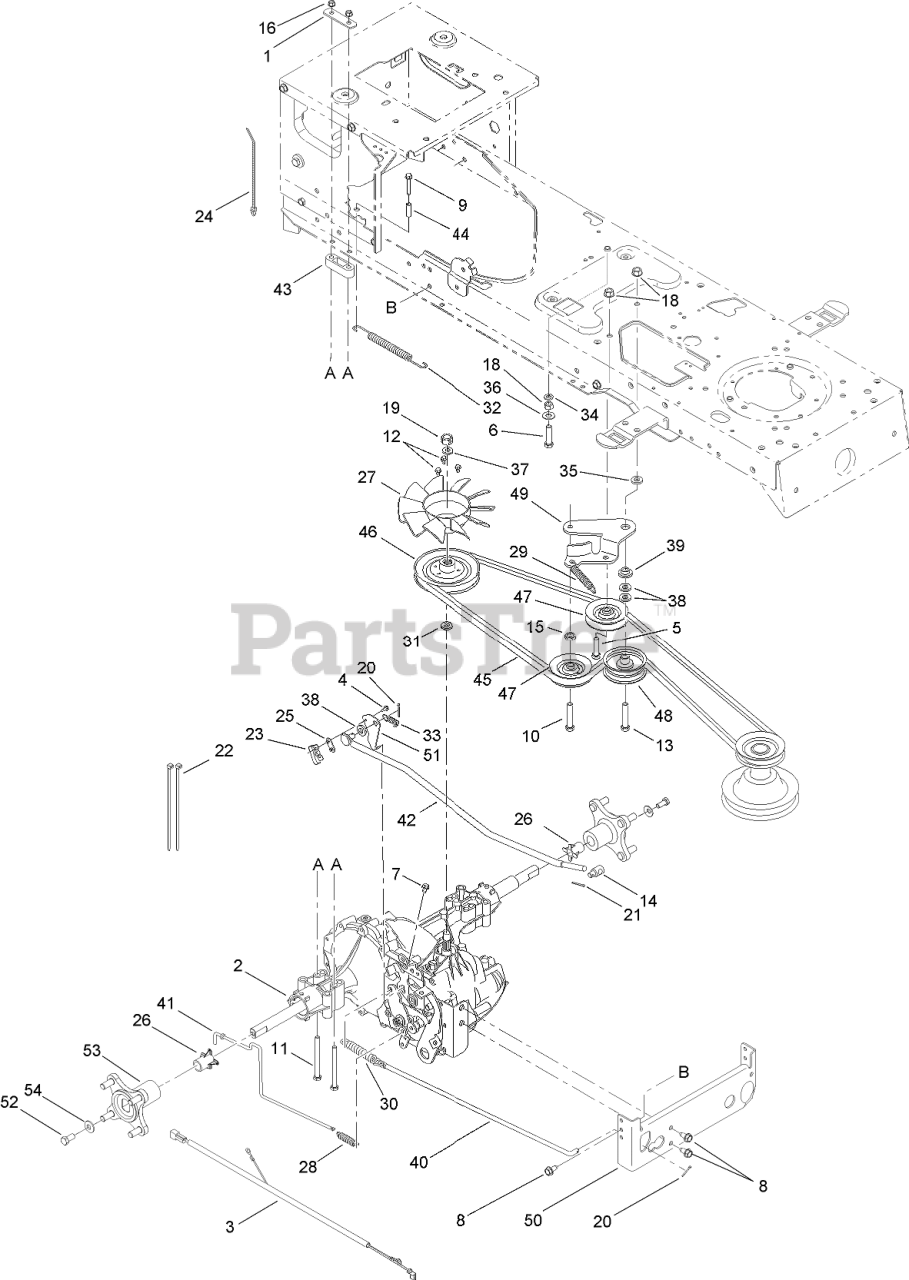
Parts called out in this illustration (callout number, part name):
1	BRACKET-MOUNTING, TRANSMISSION
2	TRANSMISSION-HYDRO
3	HARNESS ASM
4	SCREW-HWHTF
5	SCREW-HHFTF
6	SCREW-HH
7	SCREW-TAP
8	SCREW-HH, TAP
9	SCREW-HWH
10	SCREW-TAP
11	SCREW-HH
12	SCREW-HH, TAP
13	SCREW-HH
14	FERRULE
15	NUT-JAM
16	NUT-LOCK, FLANGE
18	NUT-HEX
19	NUT-HEX
20	PIN-COTTER
21	PIN-COTTER
22	TIE-CABLE
23	SWITCH-SPRING, SHORT
24	TIE-CABLE
25	PLATE-INSULATOR
26	SLEEVE
27	FAN-BLADE, 10
28	SPRING-EXTENSION
29	SPRING-EXTENSION
30	SPRING-EXTENSION
31	RING-WIRE
32	SPRING-EXTENSION
33	SPRING-EXTENSION
34	WASHER-LOCK
35	WASHER-FLAT
36	WASHER-FLAT
37	WASHER-LOCK
38	WASHER-FLAT
39	SPACER-SHOULDER
40	ROD-BRAKE
41	ROD-HYDRO
42	ROD-CONTROL
43	SPACER-TRANSAXLE
44	SPACER
45	BELT-V, TYPE
46	PULLEY-INPUT
47	PULLEY-IDLER, V-TYPE
48	PULLEY-IDLER, FLAT
49	BRACKET-IDLER, CENTER DOUBLE
50	BRACKET-TORQ, TRANSMISSION
51	BRACKET-ACTUATOR
52	SCREW-HH
53	HUB ASM
54	WASHER-BELL
